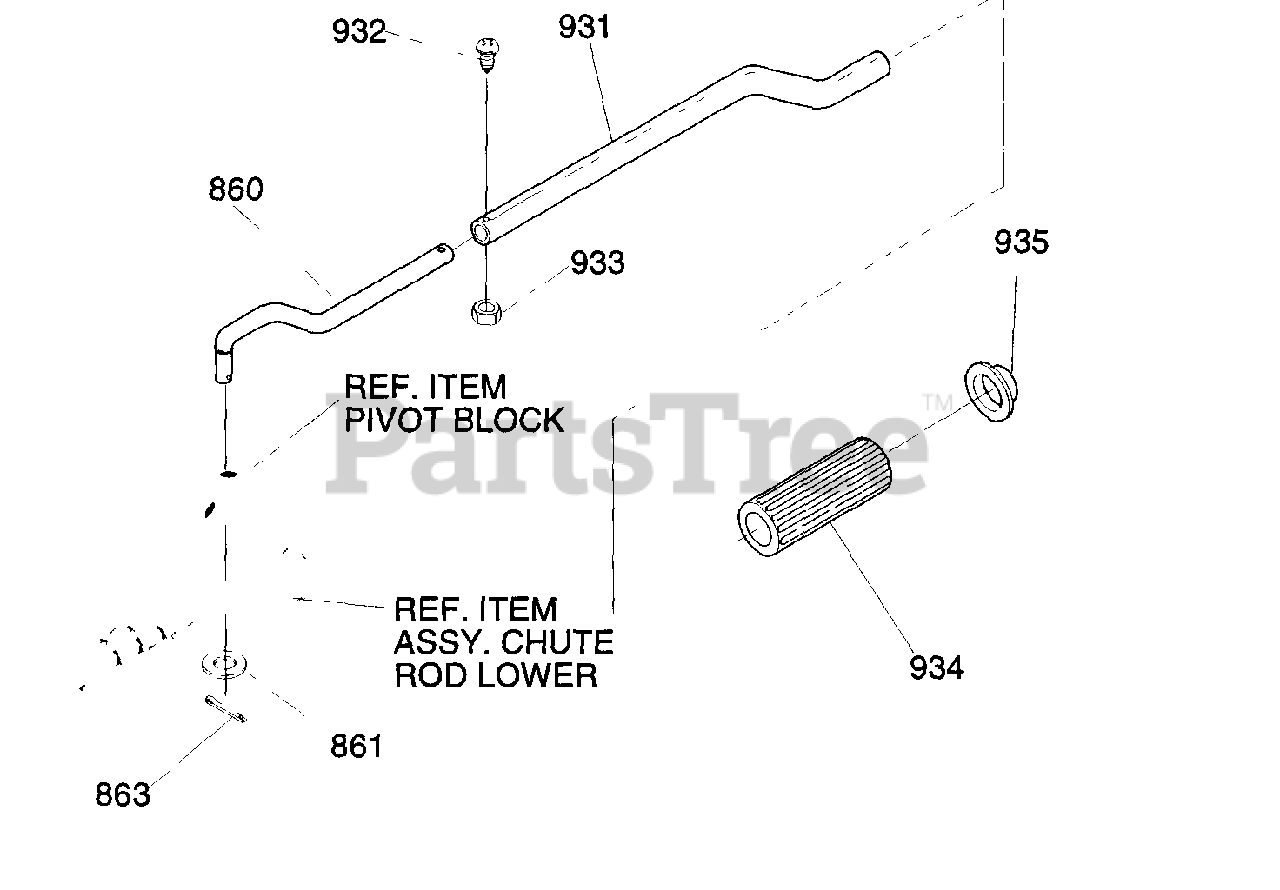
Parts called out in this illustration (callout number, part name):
860	ROD, MID CHUTE CTRL
861	FLATWASHER .40X 025
863	COTTER PIN
931	ROD CHUTE CTRL UPPER
932	SCREW 10-32X.88
933	NUT #10-32 CTRLK
934	KNOB, CHUTE CRANK
935	NUT, PUSH 3/8"
